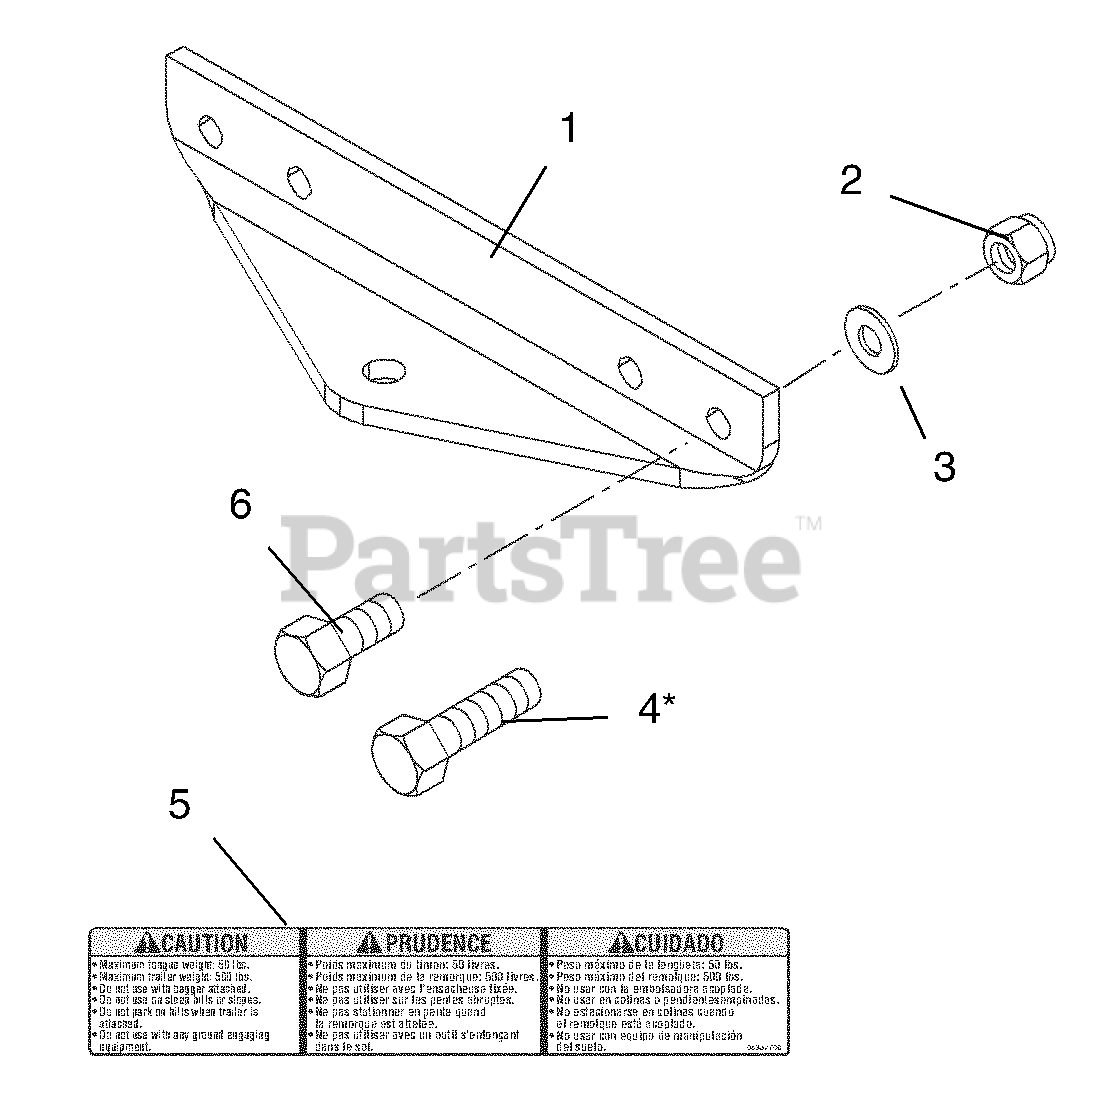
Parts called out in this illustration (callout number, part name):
1	PLT, HITCH
2	@NUT-LK-NYL .50-13 YWZC
3	WSHR-FL-STL .518X2.0X.105 YWZC
4	@BLT-HEX .50-13X3.25 GR5 YWZC
5	DECAL, TRAILER HITCH
6	@BLT-HEX .50-13X1.25 GR5 YWZC
